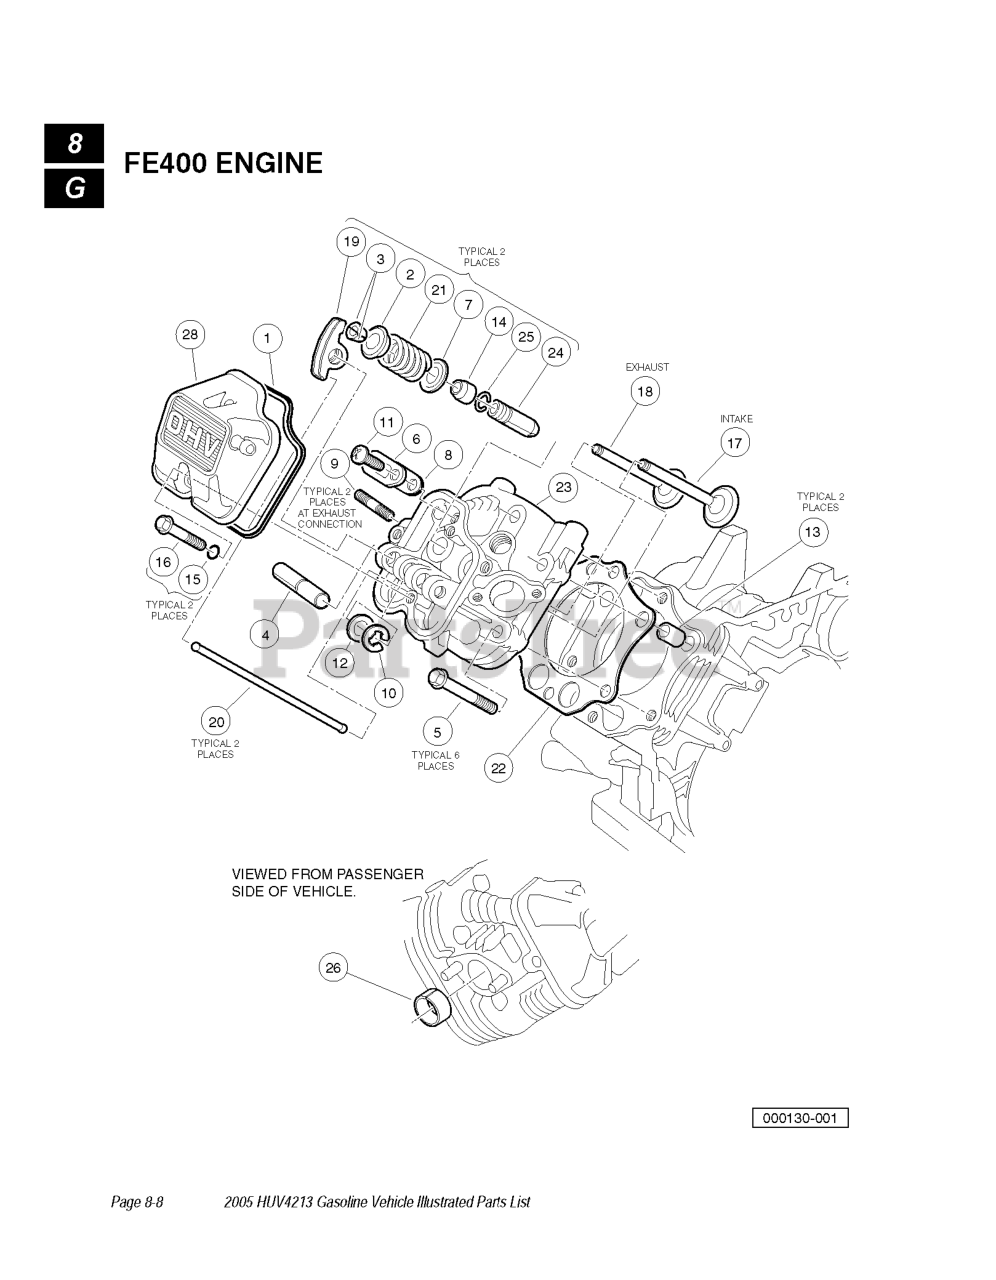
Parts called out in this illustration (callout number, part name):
1	GASKET, ROCKER CASE
2	RETAINER - VALVE SPRING
4	SHAFT - ROCKER
5	BOLT, FLANGED
7	SEAT, SPRING
9	STUD, M8-1.25 2-ENDED
10	CIRCLIP - TYPE - E
12	WASHER, 12.1X19X1.8
16	BOLT, 6X35
17	VALVE - INTAKE
18	VALVE - EXHAUST
19	ARM - ROCKER
20	ROD - PUSH
21	SPRING - ENGINE VALVE
22	FE400 HEAD GASKET
23	FE400 CYLINDER HEAD
24	GUIDE, VALVE, INTAKE
26	SLEEVE EXHAUST FE400 SPLIT
27	GASKET KIT, FE400
28	CASE, ROCKER -W/O LOGO FE290
